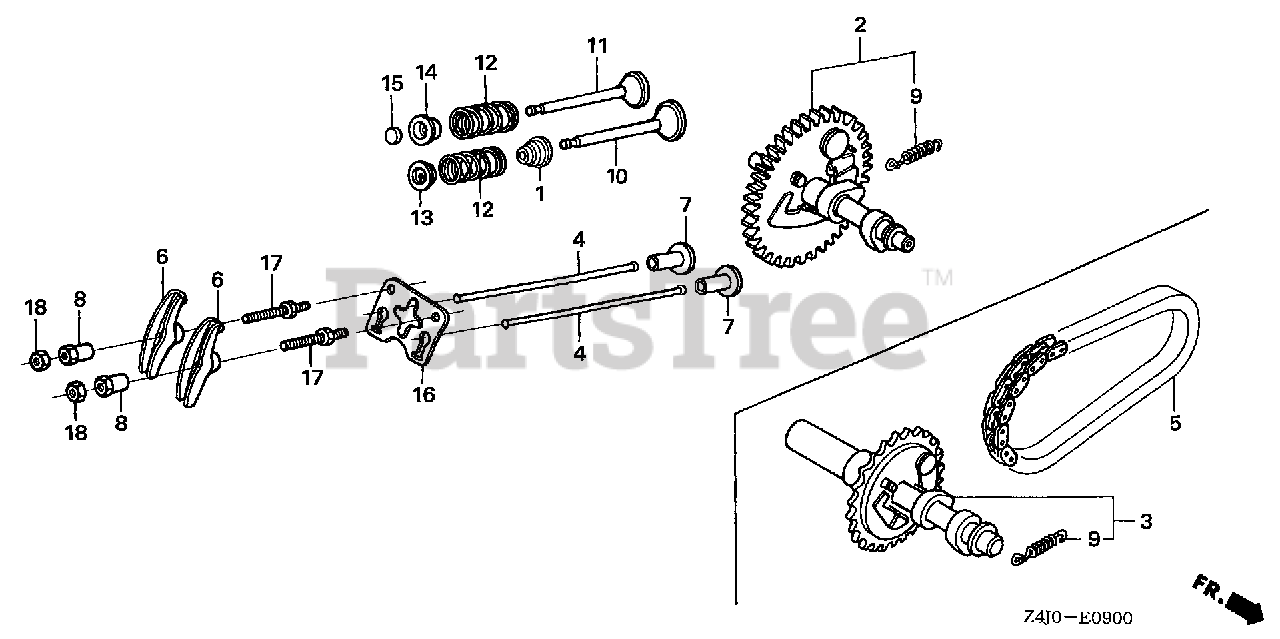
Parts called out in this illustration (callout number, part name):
1	SEAL, VALVE STEM
2	CAMSHAFT ASSY.
4	ROD, PUSH
6	ARM, VALVE ROCKER
7	LIFTER, VALVE
8	PIVOT, ROCKER ARM
9	SPRING, WEIGHT RETURN
10	VALVE, IN.
11	VALVE, EX.
12	SPRING, VALVE
13	RETAINER, IN. VALVE SPRING
13	RETAINER, VALVE SPRING (EXHAUST SIDE)
14	RETAINER, EX. VALVE SPRING
15	ROTATOR, VALVE
16	PLATE, PUSH ROD GUIDE
17	BOLT, PIVOT (8MM)
18	NUT, PIVOT ADJ.
